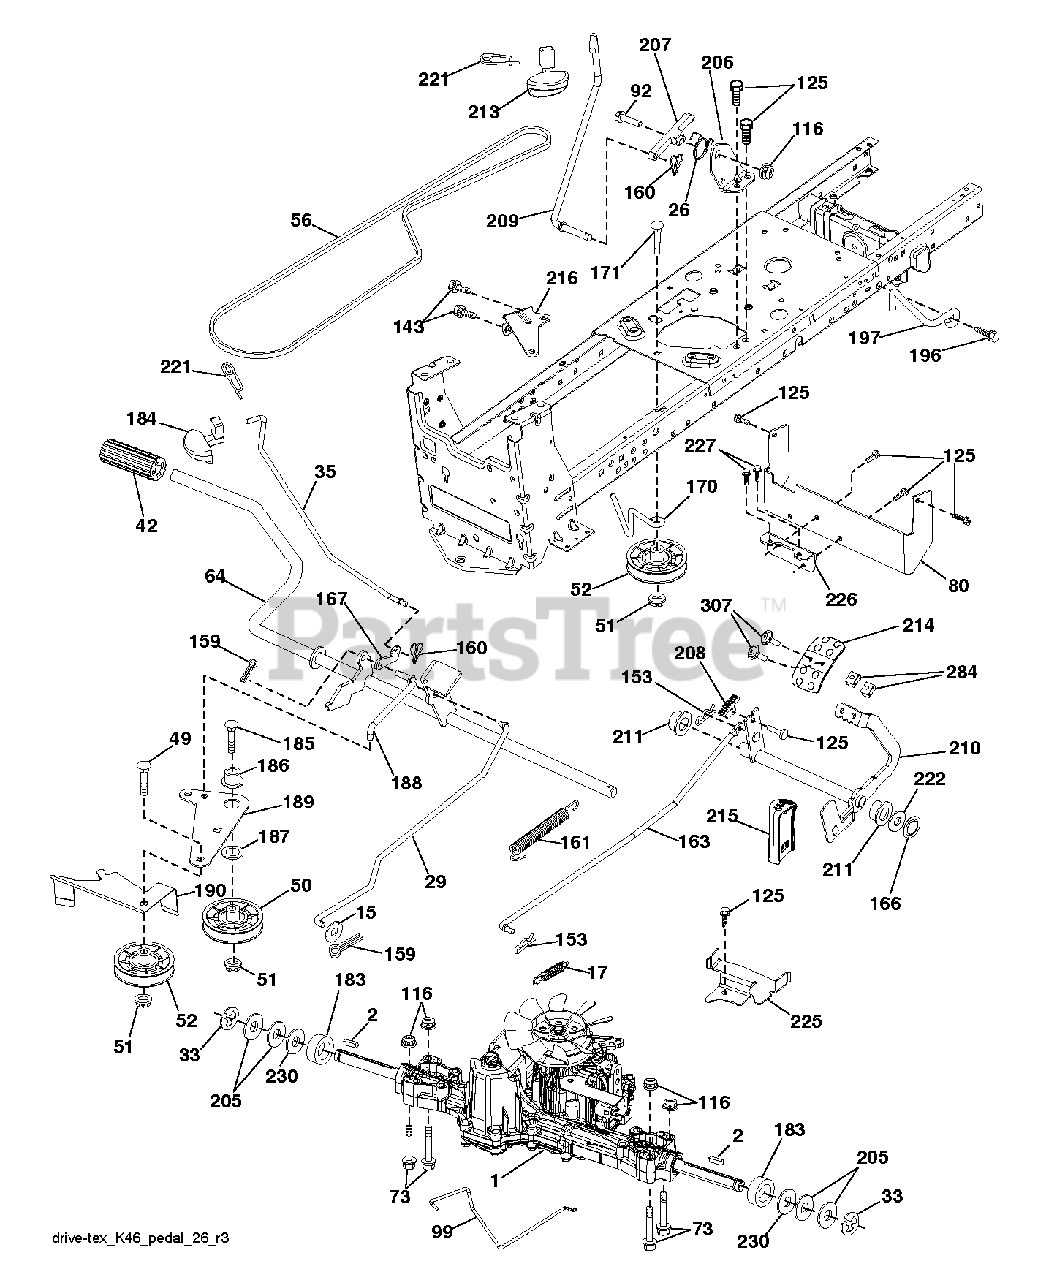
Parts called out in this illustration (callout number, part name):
2	SQUARE KEY
15	WASHER
17	SPRING.BRAKE.K46.GREEN
26	SPRING.RETURN.CRUISE
29	ROD.BRAKE.K46
35	ROD .BRAKE. PARKING. GT. HUSQ.
42	PEDAL COVER T
50	IDLER.FLAT.910.OFFSET
51	NUT LOCK FLG 3/8-16 UNC
52	IDLER.V-GROOVE.910.OFFSET
56	V-BELT.MOWER.92.40.42/K46
64	SHAFT.ASM.PEDAL.BRK.CNTR
80	STRAP.TORQUE.K46.K57R.TT
92	BOLT
99	ROD.SPRING.BYPASS.K46.LT.Z
116	NUT LOCK HEX FLANGE 5/16-18
125	SCREW
143	SCREW LT
153	RETAINER M
159	COTTER PIN
160	RETAINER CLIP
161	SPRING, RETURN LT
163	ROD.CONTROL.K57R.K46
166	NUT.PUSH.625
167	LATCH.BRAKE.SPRING
170	KEEPER.V-IDLER.CENTER.
183	SPACER AXLE
184	RB HANDLE.PARKG.BRK.HUS/PRED
186	SPACER.RETAINER
187	WASHER 12/32X2X10GA
188	RP LINK.CLUTCH.GROUND.DRIVE
189	BELLCRANK.GROUND.DRIVE.TEX.
190	KEEPER.BELLCRANK.DRIVE
196	SCREW 3/8-16X1
197	LINK.CLUTCH.ANIT-ROTAT
206	BRACKET.MOUNT.CRUISE.LATCH
207	LATCH.CONTROL.CRUISE
208	GEAR.SECTOR.CONTROL.CR
209	ROD.CONTROL.CRUISE.GT.
210	ROCKER.ASM.PEDAL.CONTR
211	BEARING.NYLON
213	KNOB.CONTROL.CRUSIE.HU
214	PEDAL.FORWARD.HUSQVARNA.DEALER
215	PEDAL.REVERSE.TEX.GT.4
216	BRACKET.PULLEY.IDLER.W/TEX
221	RETAINER.SPRING.CLIP.H
222	WASHER 21/32 X 1-1/4 X 10 GA.
225	KEEPER.BELT.TRANSAXLE.K46
226	BRACKET.MOUNT.TORQUE.K46.TLT
227	SCREW
230	WASHER.HARDENED
284	NUT.U-CHNL.1/4-20.550DP.350PNL
